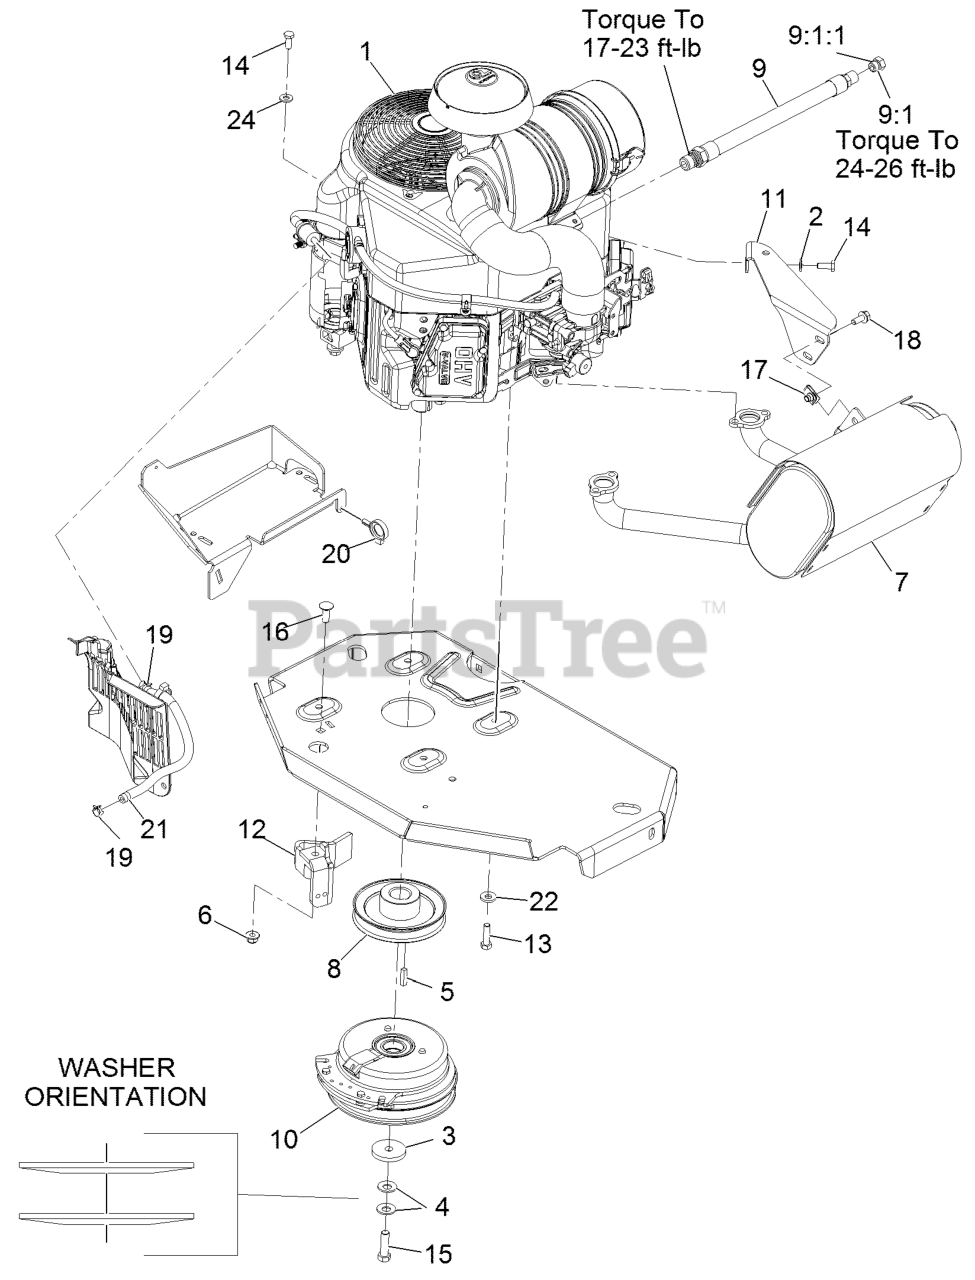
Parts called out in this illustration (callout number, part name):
2	WASHER-SPRING
3	WASHER-CLUTCH
4	WASHER-SPRING
6	NUT-HF, NI
7	MUFFLER
8	SHEAVE-PUMP, DRIVE
9	ENGINE OIL DRAIN HOSE ASM
9:1	PLUG-HH
9:1:1	O-RING
11	BRACKET-MUFFLER
12	CLUTCH-ANCHOR
13	SCREW-HH
14	SCREW-HH
15	SCREW-HH 7/16-20 X 1 1/2 W/LOCTITE
16	SCREW-CARR
18	SCREW-HHF
19	CLAMP-HOSE
20	CLAMP-HOSE
21	HOSE-FUEL
22	WASHER-BELLEVILLE
24	WASHER-PLAIN
